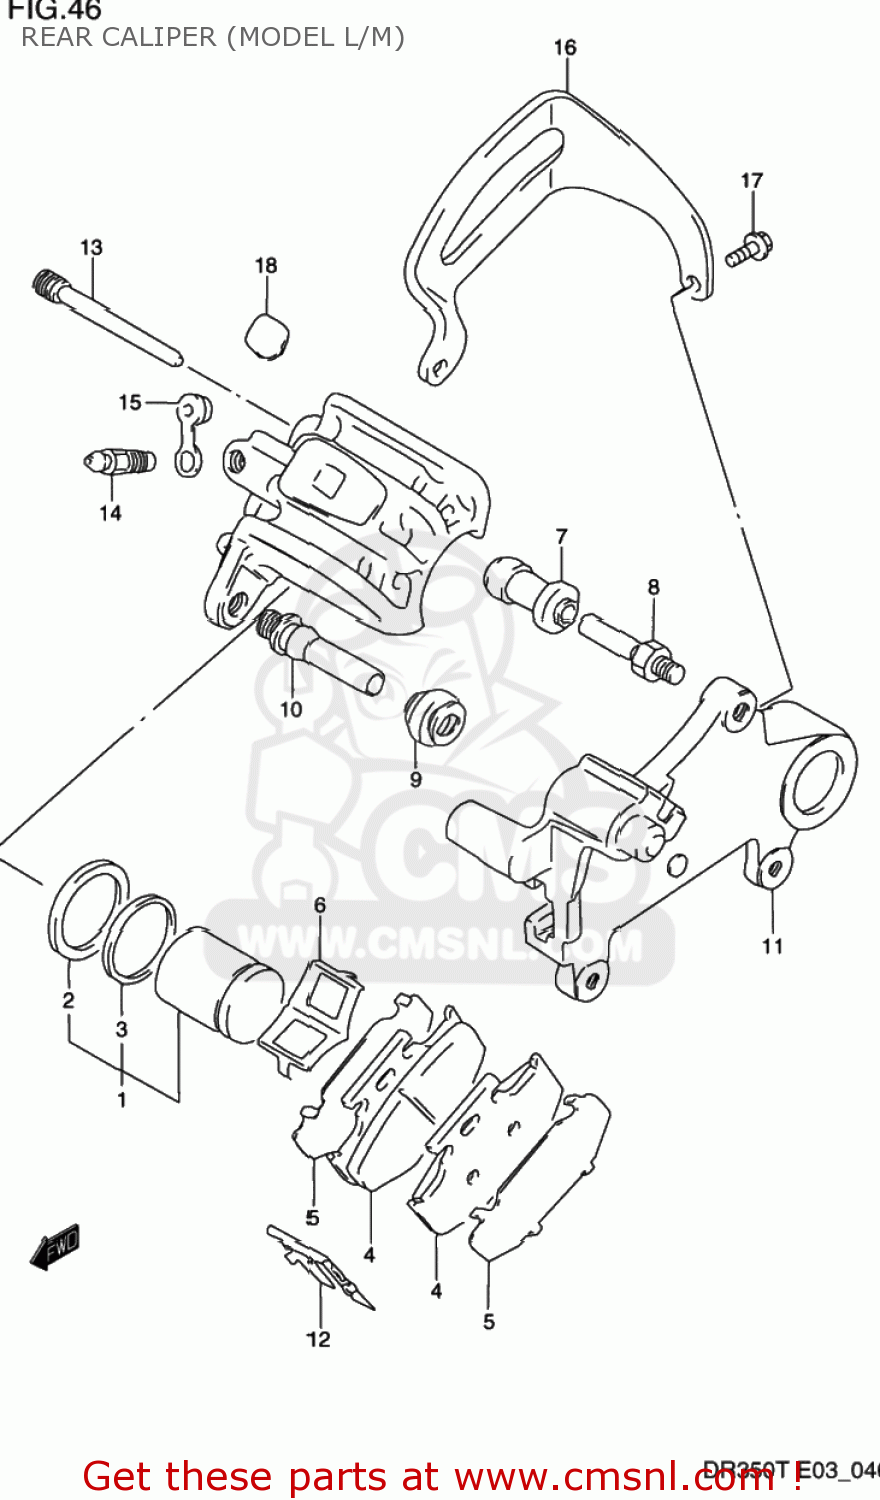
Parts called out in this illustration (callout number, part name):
1	PISTON SET
2	SEAL,PISTON
3	SEAL,DUST
4	PAD
5	SHIM
6	SPRING,PAD
7	BOOT
8	PIN,BOLT
9	BOOT
10	PIN
11	BRACKET
12	RETAINER
13	PIN,HANGER
14	BLEEDER
15	CAP,BLEEDER
16	GUARD,RR CALIPER
17	BOLT
18	COVER,RR CALIPER BODY
